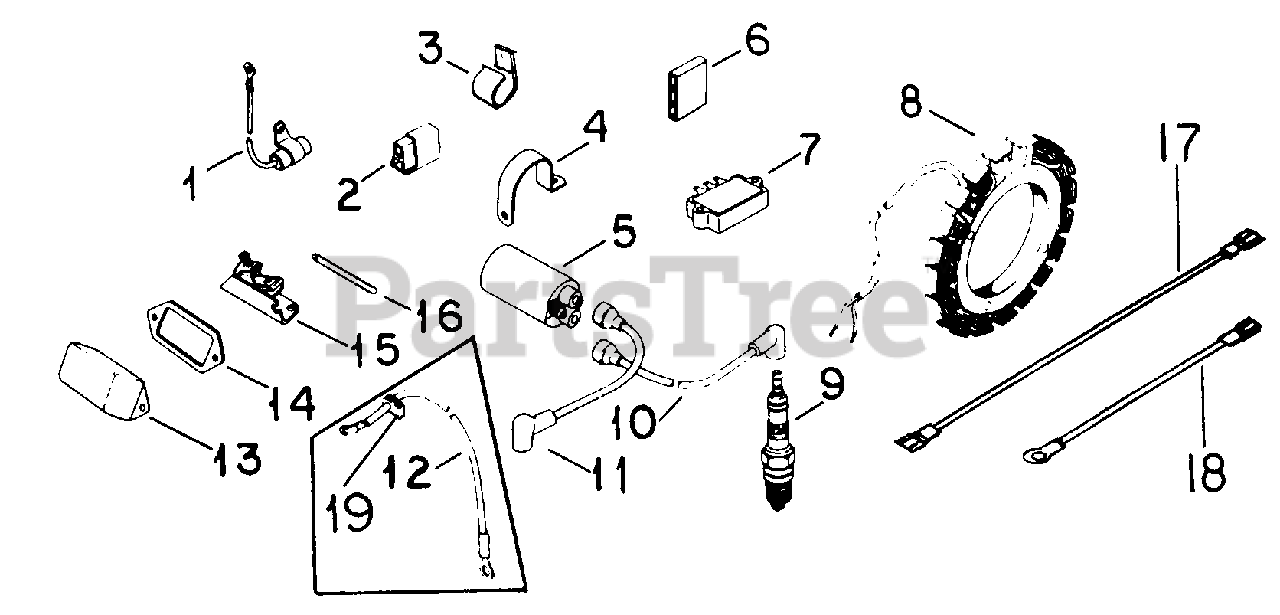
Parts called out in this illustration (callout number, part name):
3	Clip, Cable
5	Kit, Ignition Coil
6	Connector
7	Rectifier, Regulator
8	Stator Assy
9	Spark Plug
10	Cable Assy, Hi-Tension 19 In.
11	Cable Assy, Hi-Tension 11 In.
12	Cable, Coil to Breaker Points
13	Cover, Breaker
14	Gasket, Cover
15	Breaker, Ignition Points
16	Rod, Breaker Push
17	Wire, Regulator/Rectifier Lead, 16 In.
18	Wire, Coil, 6 In.
